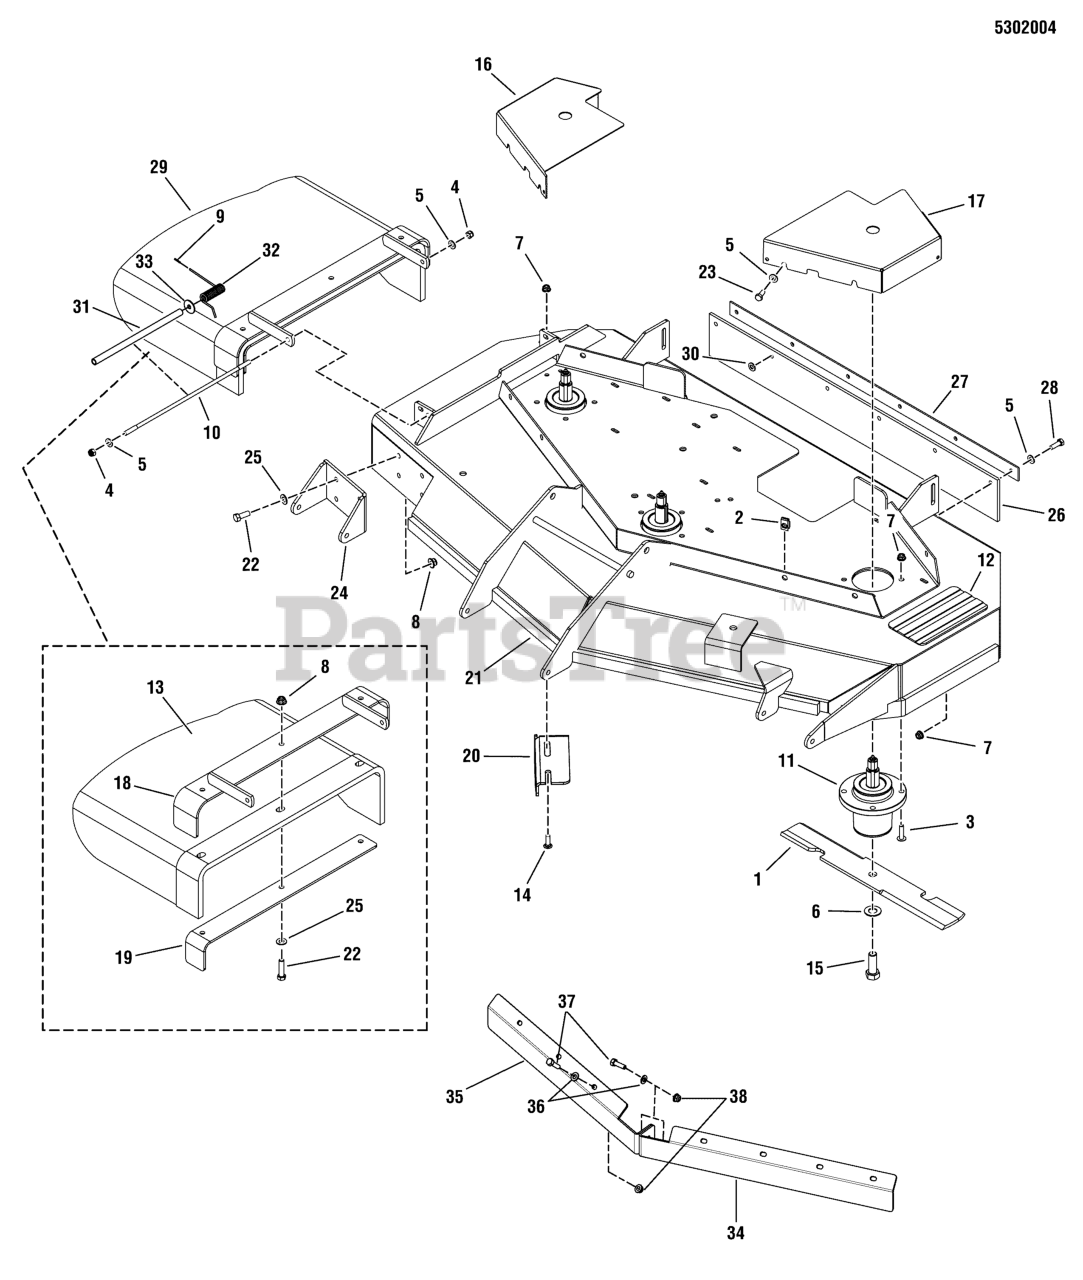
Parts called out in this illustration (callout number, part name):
1	BLADE, 18 X .25 X 2.5, 1 X 3.5 (SET OF 3)
2	BODY CLIP, 5/16-18-7GA MATERIAL
3	BOLT, 5/16-18 X 1 1/4 FLANGE
4	NUT, 5/16-24 HEX NYLON LOCK
5	WASHER, 5/16" SAE
6	WASHER, 5/8 GRADE 8, YZ
7	NUT, 5/16-18 HEX NYLOCK FLANGE
8	NUT, 3/8-16 HEX NYLOCK FLANGE
9	CAP, PROTECTOR, .120 ID
10	ROD MOUNT, CHUTE 61"
11	ASSM, SPINDLE, LOW PROFILE
12	SAFETY WALK, 4.00 X 7.50
13	CHUTE, DISCHARGE, RUBBER, 61/72
14	BOLT, 5/16-18 X 3/4, CARRIAGE
15	BOLT, 5/8-11 X 1-3/4 GD8
16	GUARD, 52 DECK, RH - RED
17	GUARD, 52" DECK - LH - RED
18	WELD, FRAME, CHUTE, 61 - SNP RED
19	SUPPORT, DISCHARGE CHUTE - BLK
20	PLATE, DEFLECTOR - BLK
21	DECK SHELL W/ DECALS, 52, S150XCE
22	BOLT, 3/8-16 X 1-1/4" GD5 CZ
23	BOLT, 5/16-18 X 3/4 GD5
24	WELD,BRACKET, ANTI SCALP - RED
25	WASHER, 3/8 SAE
26	FLAP, STRIPER, 52 DECK
27	PLATE, SUPPORT - BLK
28	BOLT, 5/16-18 X 1 GD5 YZ
29	KIT, DISCHARGE CHUTE
30	5/16 PUSH-ON NUT RETAINER, STL, CZ
31	SPACER, TORSION SPRING,9.63 LG
32	SPRING, TORSION
33	WASHER, 5/16 FENDER
34	BAFFLE, FRONT DISCHARGE, LH,S150XCE, RED
35	BAFFLE, FRONT DISCHARGE, RH,S150XCE, RED
36	WASHER, 5/16" SAE
37	BOLT, 5/16-18 X 1 GD5 YZ
38	NUT, 5/16-18 HEX NYLOCK FLANGE
